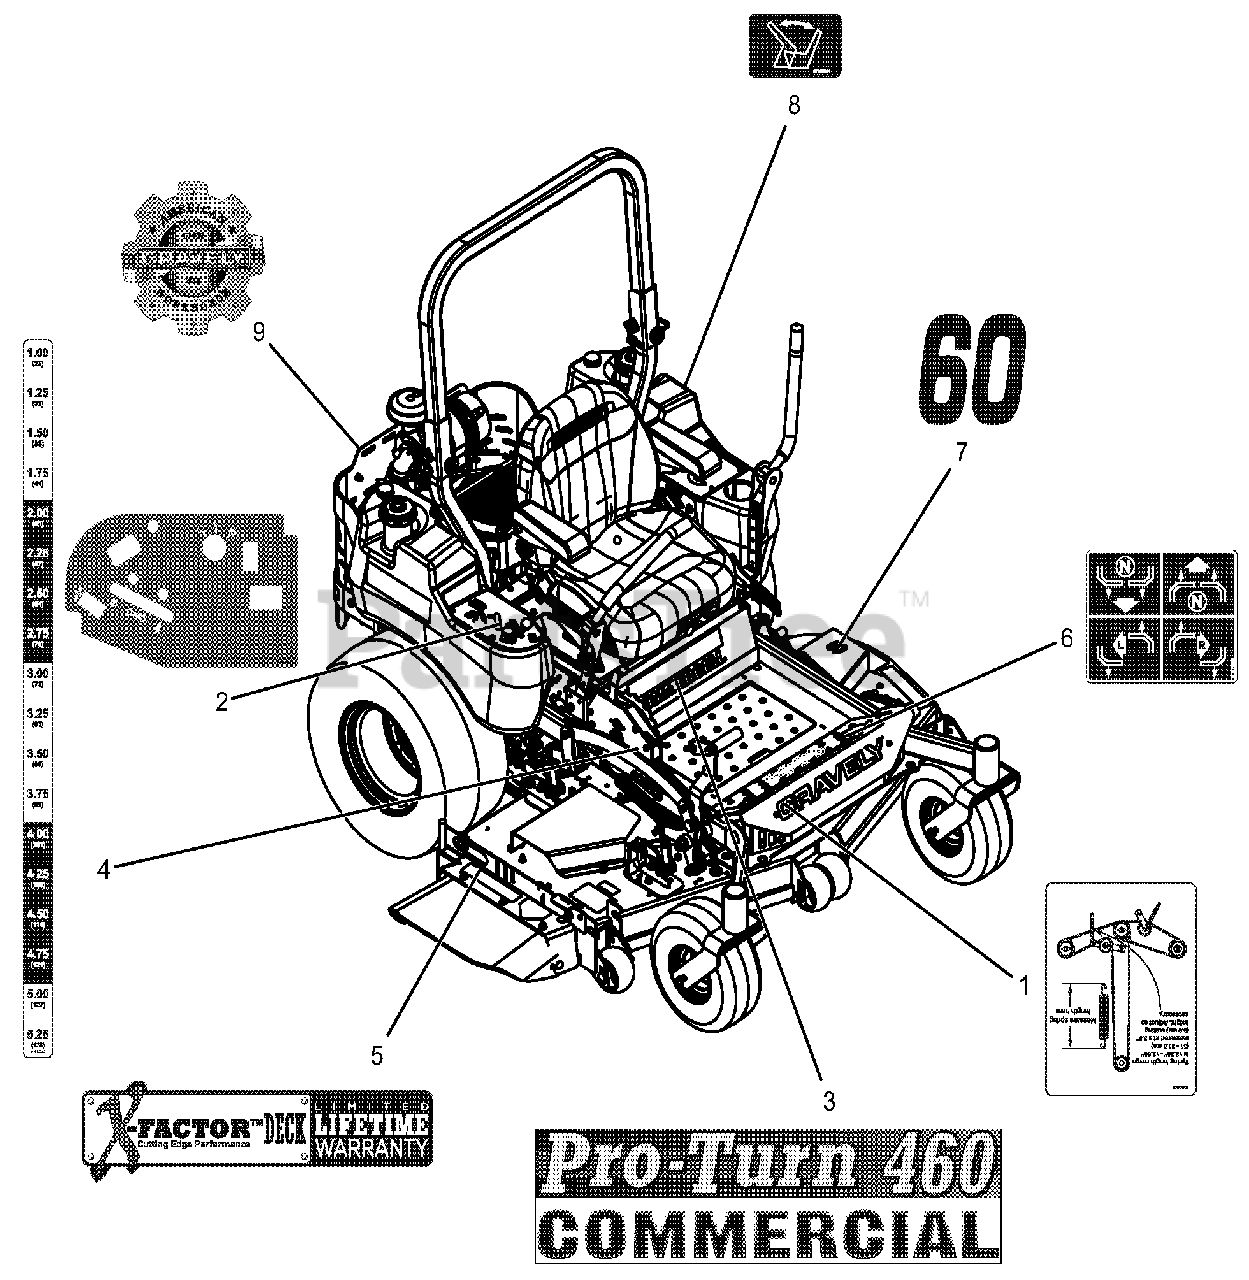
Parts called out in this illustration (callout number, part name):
1	DECAL, BELT ROUTING
2	DECAL, CONTROL PANEL
3	DECAL, PT460
4	DECAL, PT400 HEIGHT OF CUT
5	DECAL, X-FACTOR DECK
6	DECAL, INSTRUCTIONAL - STEERING
7	DECAL, 60"
8	DECAL, SEAT RELEASE
9	DECAL, GRAVELY HERITAGE-LARGE
